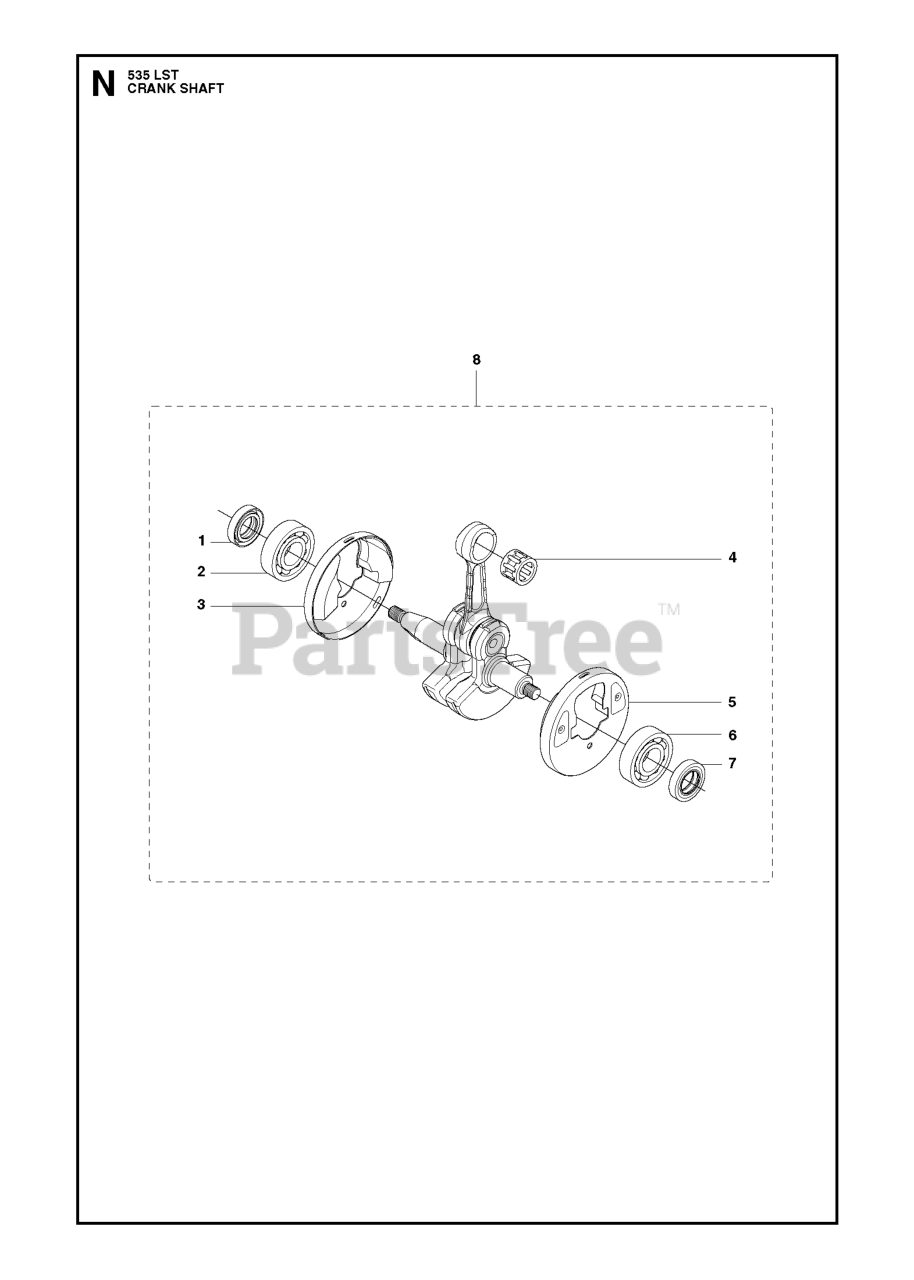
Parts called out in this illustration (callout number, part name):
1	SEALING RING
2	BALL BEARING
4	SUPPORT BUSHING
6	BALL BEARING
7	SEALING RING
8	CRANKSHAFT
